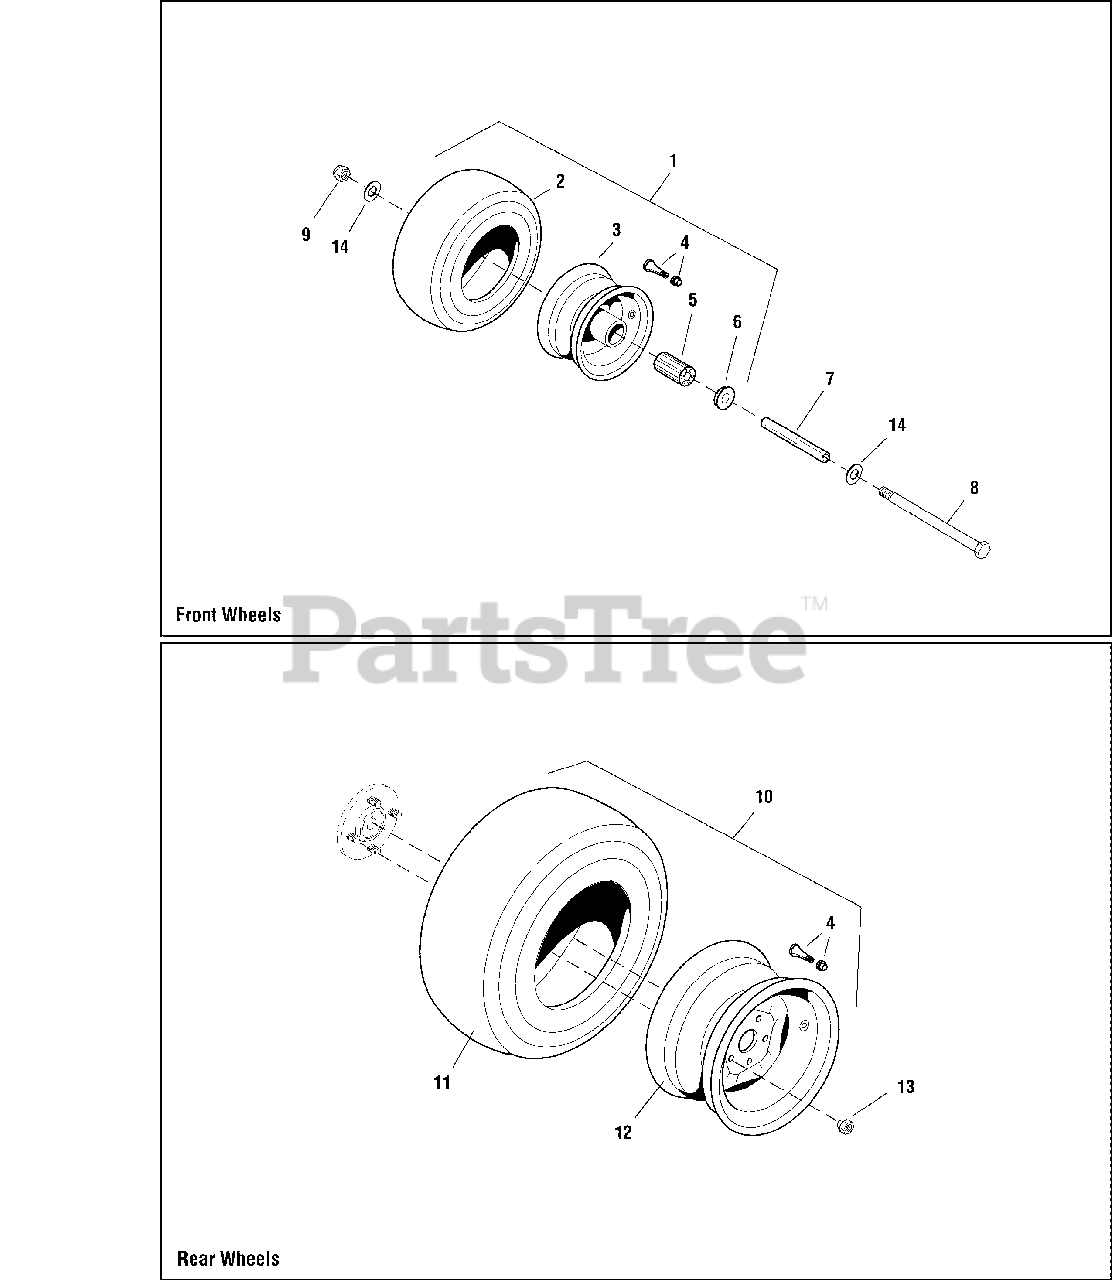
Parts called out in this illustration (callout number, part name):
2	TIRE, FRONT, 11 X 4.0 - 5
3	WHEEL ASSEMBLY, COMPLETE
4	VALVE STEM & CAP ASSEMBLY
5	BEARING, ROLLER
6	BEARING RETAINER
7	AXLE, FRONT CASTER
8	BOLT, 1/2-13 X 6-1/2
9	NUT, HEX NYLON LOCK, 1/2-13
10	TIRE ASSM, 20X8.00-10NHS, TURF MASTER
11	TIRE, Rear 20 X 8.0 X 10, TURF MASTER
12	WHEEL, 10X7.00 4/4 SOLID F237 2.625 OS (SV)
13	LUG NUT, 1/2-20
14	WASHER, SAE, 1/2
